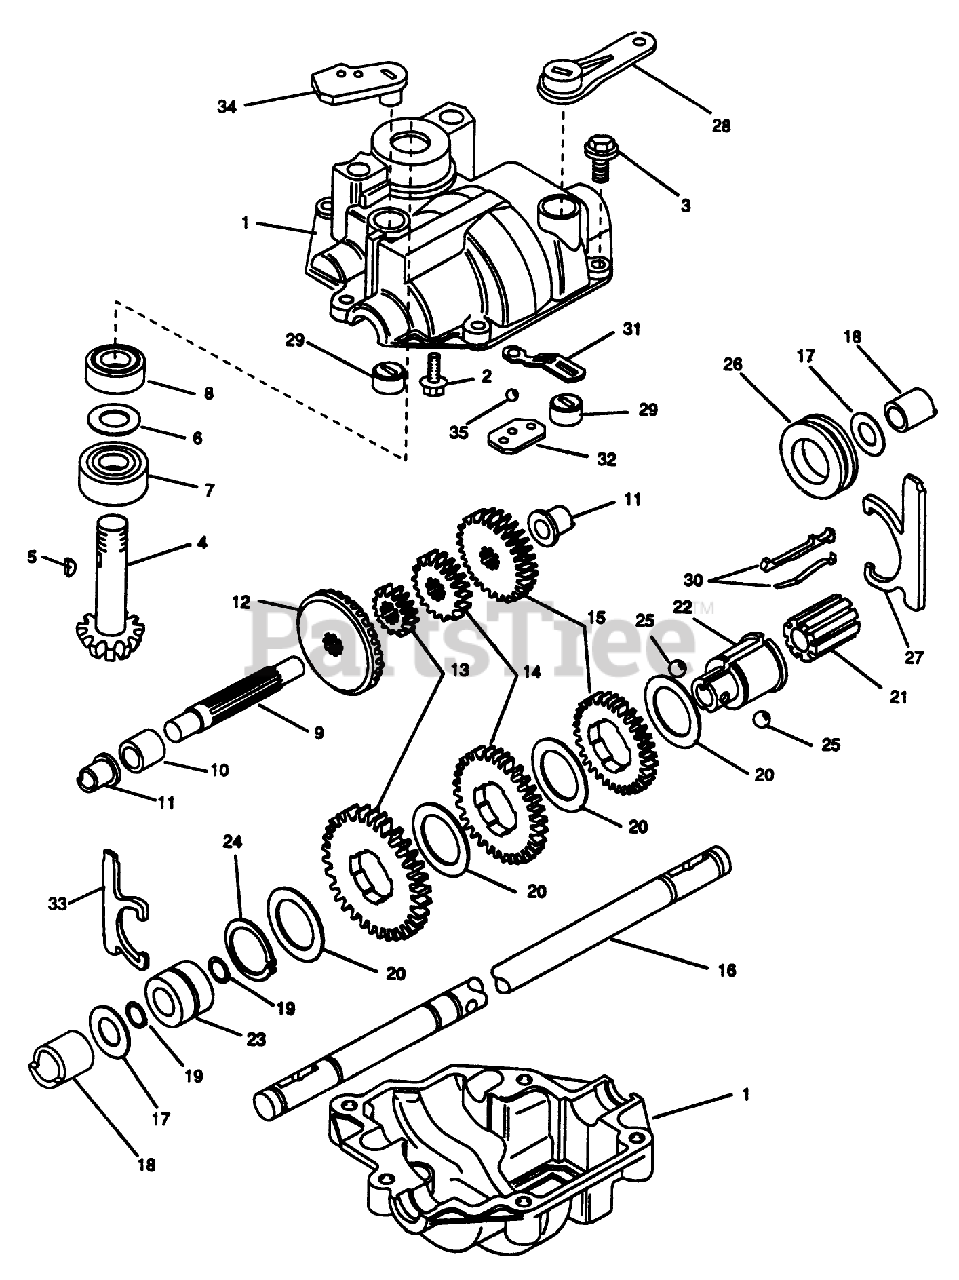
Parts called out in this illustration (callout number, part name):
5	KEY GALGER
7	BEARING
8	BEARING
12	GEAR-RING
22	COLLAR-SHFT
34	ARM - CLUTCH
